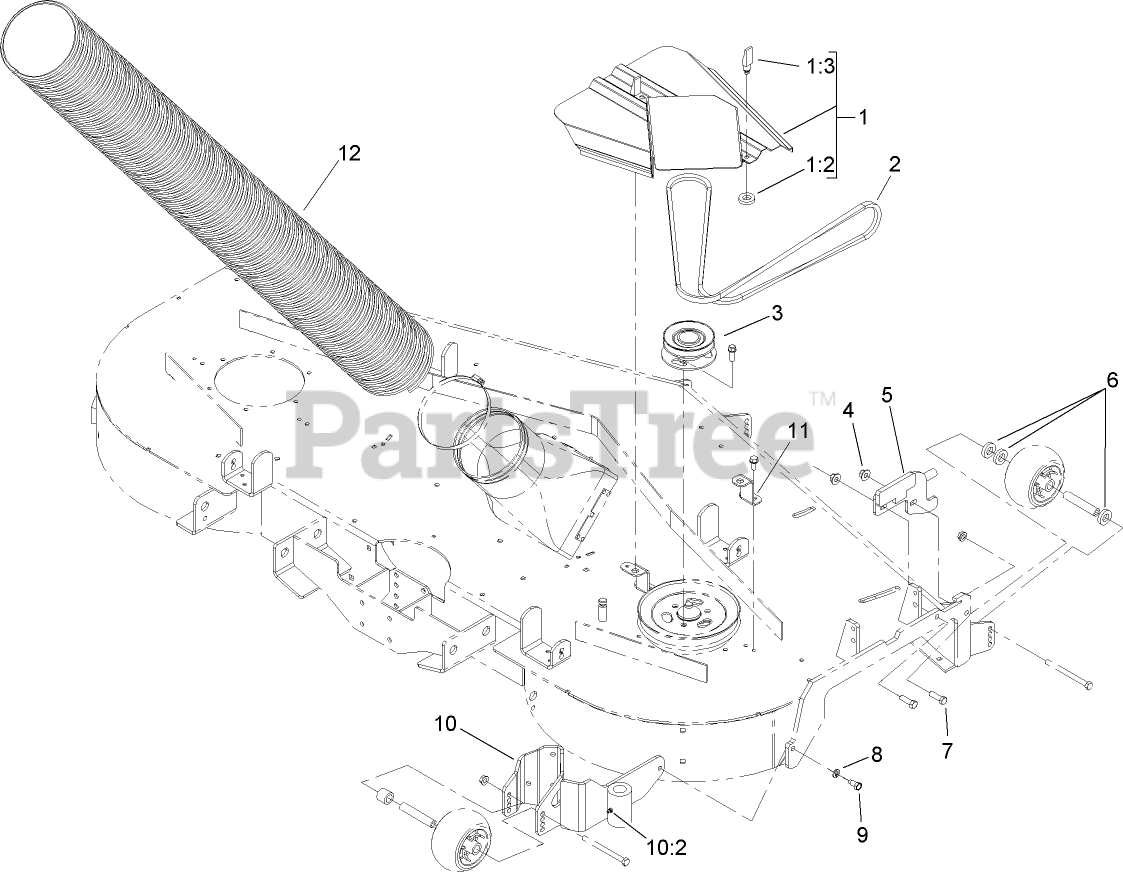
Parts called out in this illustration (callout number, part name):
1	LATCH AND COVER ASM
1:2	WASHER
1:3	LATCH-SWELL
2	Belt-V
3	PULLEY ASM
4	NUT-FLANGE
5	FRONT HINGE ASM
6	SPACER
7	SCREW-HH
8	WASHER-LOCK
9	SCREW-HH, TAP
10	REAR HINGE ASM
10:2	FITTING-GREASE
11	BRACKET COVER
12	HOSE-FLEXIBLE
